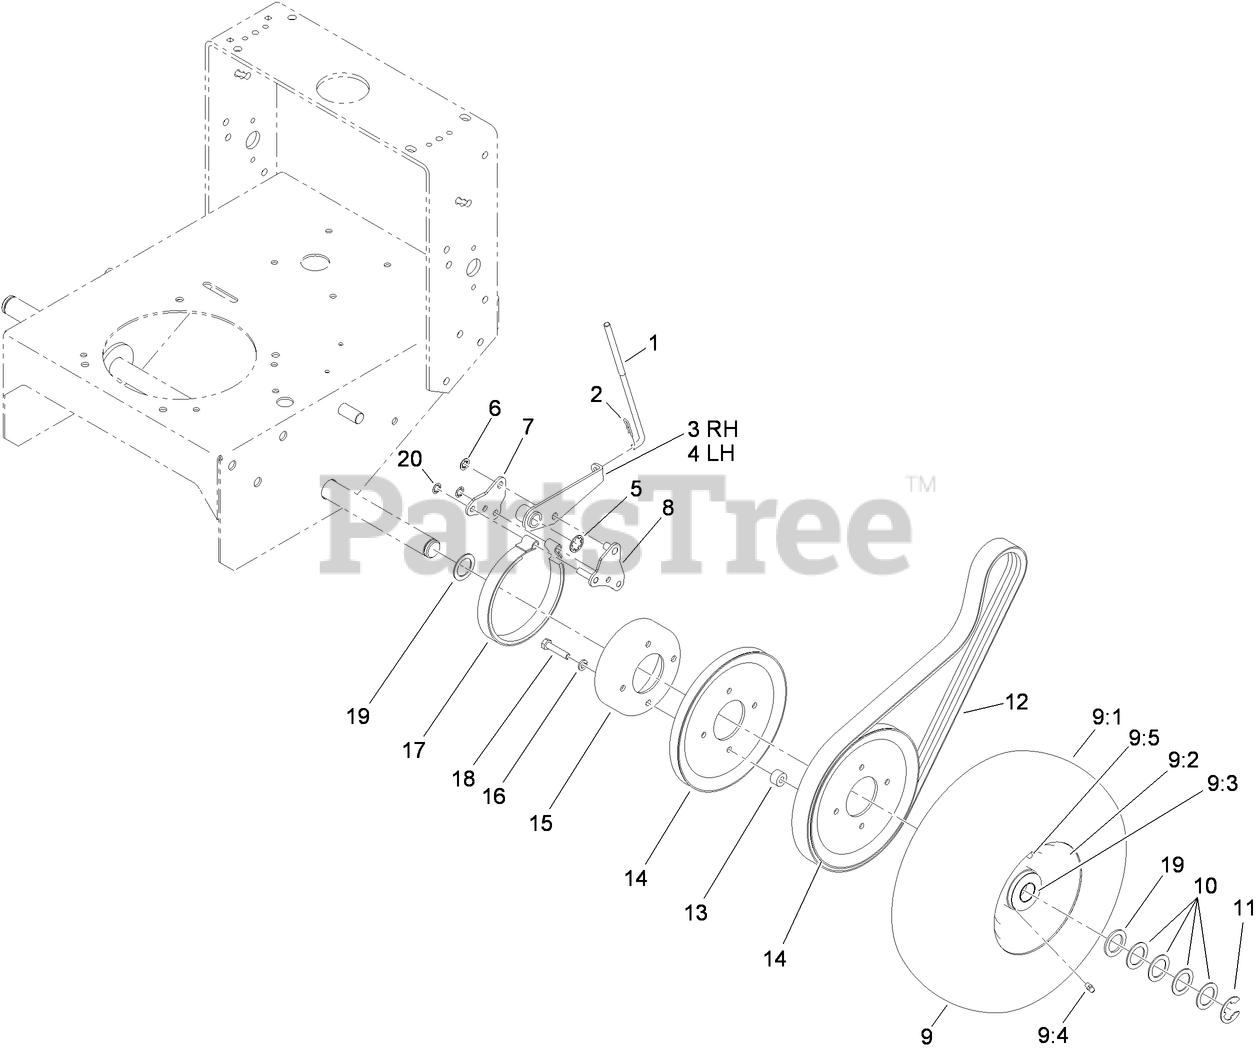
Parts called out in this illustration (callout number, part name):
1	ROD-BRAKE
2	PIN-COTTER
3	ARM-BRAKE, RH
4	ARM-BRAKE, LH
5	RING-RETAINING
6	RING-RETAINING, EXTERNAL
7	PLATE-LINK, BRAKE
8	LINK-BRAKE
9	WHEEL AND TIRE ASM
9:1	TIRE-FRONT
9:2	WHEEL ASM
9:3	BEARING-BALL
9:4	FITTING-GREASE
9:5	STEM-VALVE
10	WASHER-THRUST
11	RING-SNAP
12	V-BELT
13	SPACER-PULLEY
14	PULLEY-WHEEL
15	DRUM-BRAKE
16	WASHER-LOCK
17	BAND-BRAKE
18	SCREW-HH
19	WASHER-WHEEL
20	RING-RETAINING
